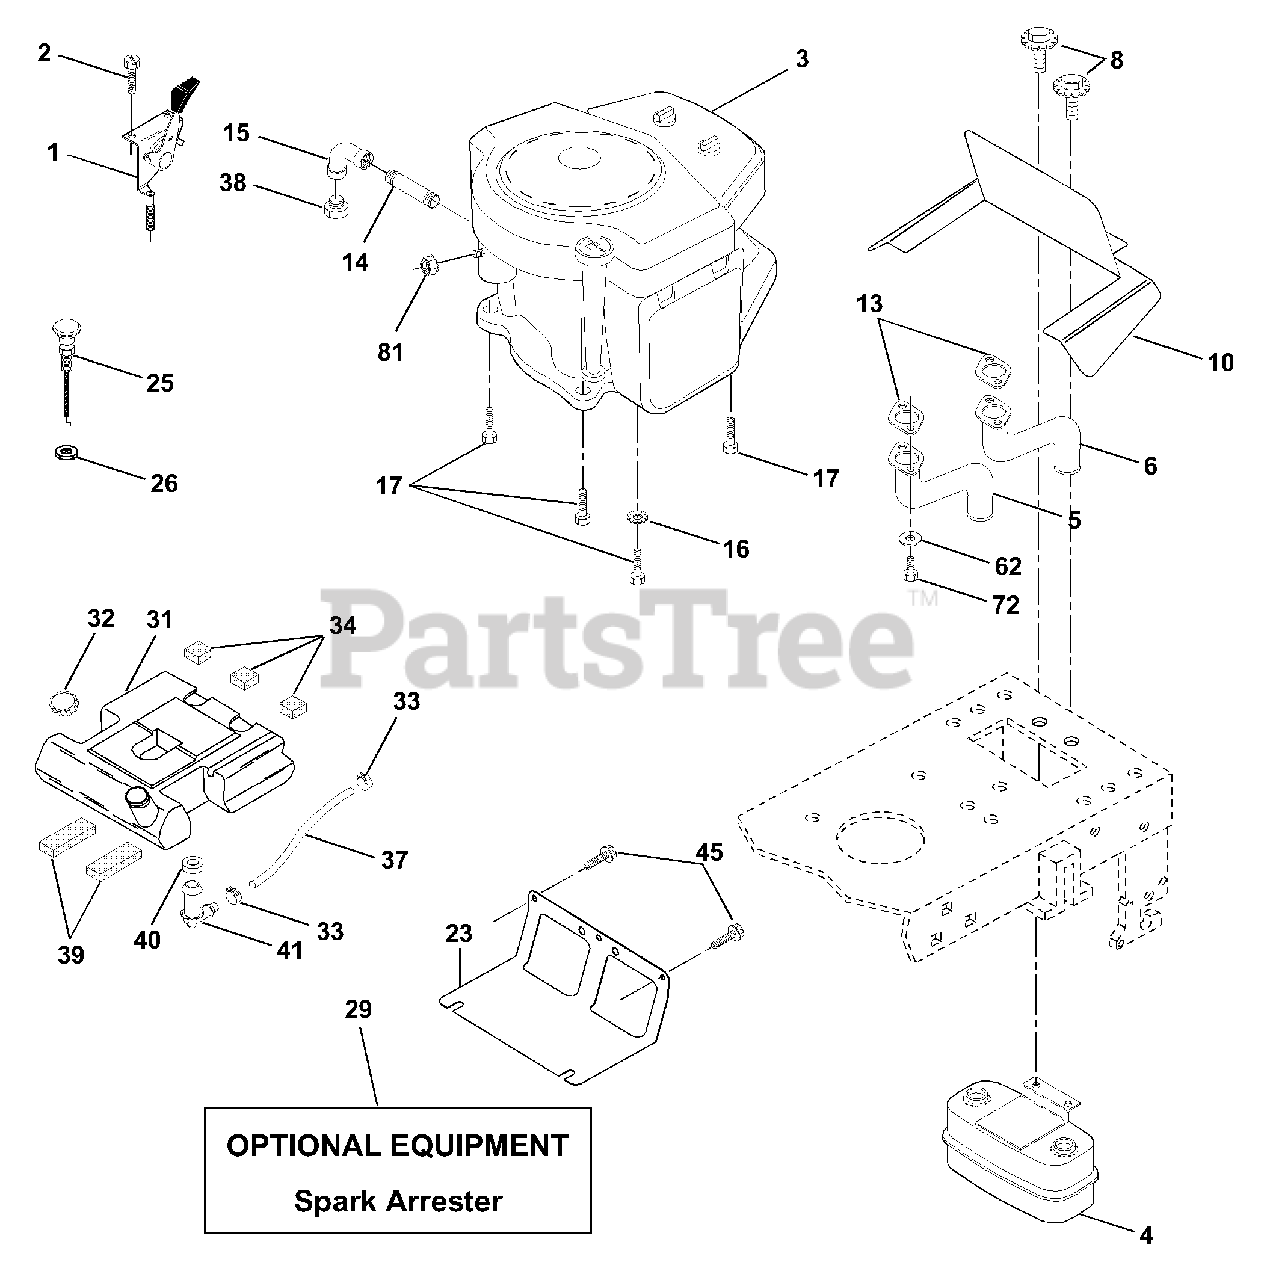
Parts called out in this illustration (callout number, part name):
1	Control Th/Flag 180 LH 36"
2	Screw Hex Thd Cut 1/4-20x5/8 T
4	Muffler Asm Twin Lo-Tone
5	Pipe Exhaust LH Intek
6	Pipe Exhaust RH Intek
8	Bolt 5/16-18 UNC x 3/4 w/Sems
10	Shield Browning Intek II
13	Muffler Gasket
14	Nipple Pipe 3/8 Npt X 4-1/2"
15	Elbow Std 90 Degree 3/8-18 Npt
16	Washer Lock Ext Tooth 3/8
17	Screw Thdrol 3/8-16 x 1-1/2
23	Shield Heat
25	Choke Control 37"
26	Nut, Keps 3/8-24 UNF
29	Kit Spark Arrestor (Flat Scrn)
31	Tank Fuel 3 50 Rear YTGT
32	Cap Asm Fuel W/sym Vented
33	Clamp Hose Black
34	Pad, Spacer
37	Line Fuel
38	Plug Oil Drain
39	Pad, Idler
40	Bushing
41	Stem Tank Fuel
45	Screw Hexwsh Thdr 3/8-16 x 3/4
62	Washer Lock 5/16
72	Screw Hex Hd Cap 5/16-18 x 3/4
81	Nut Keps Hex 1/4-20 UNC
